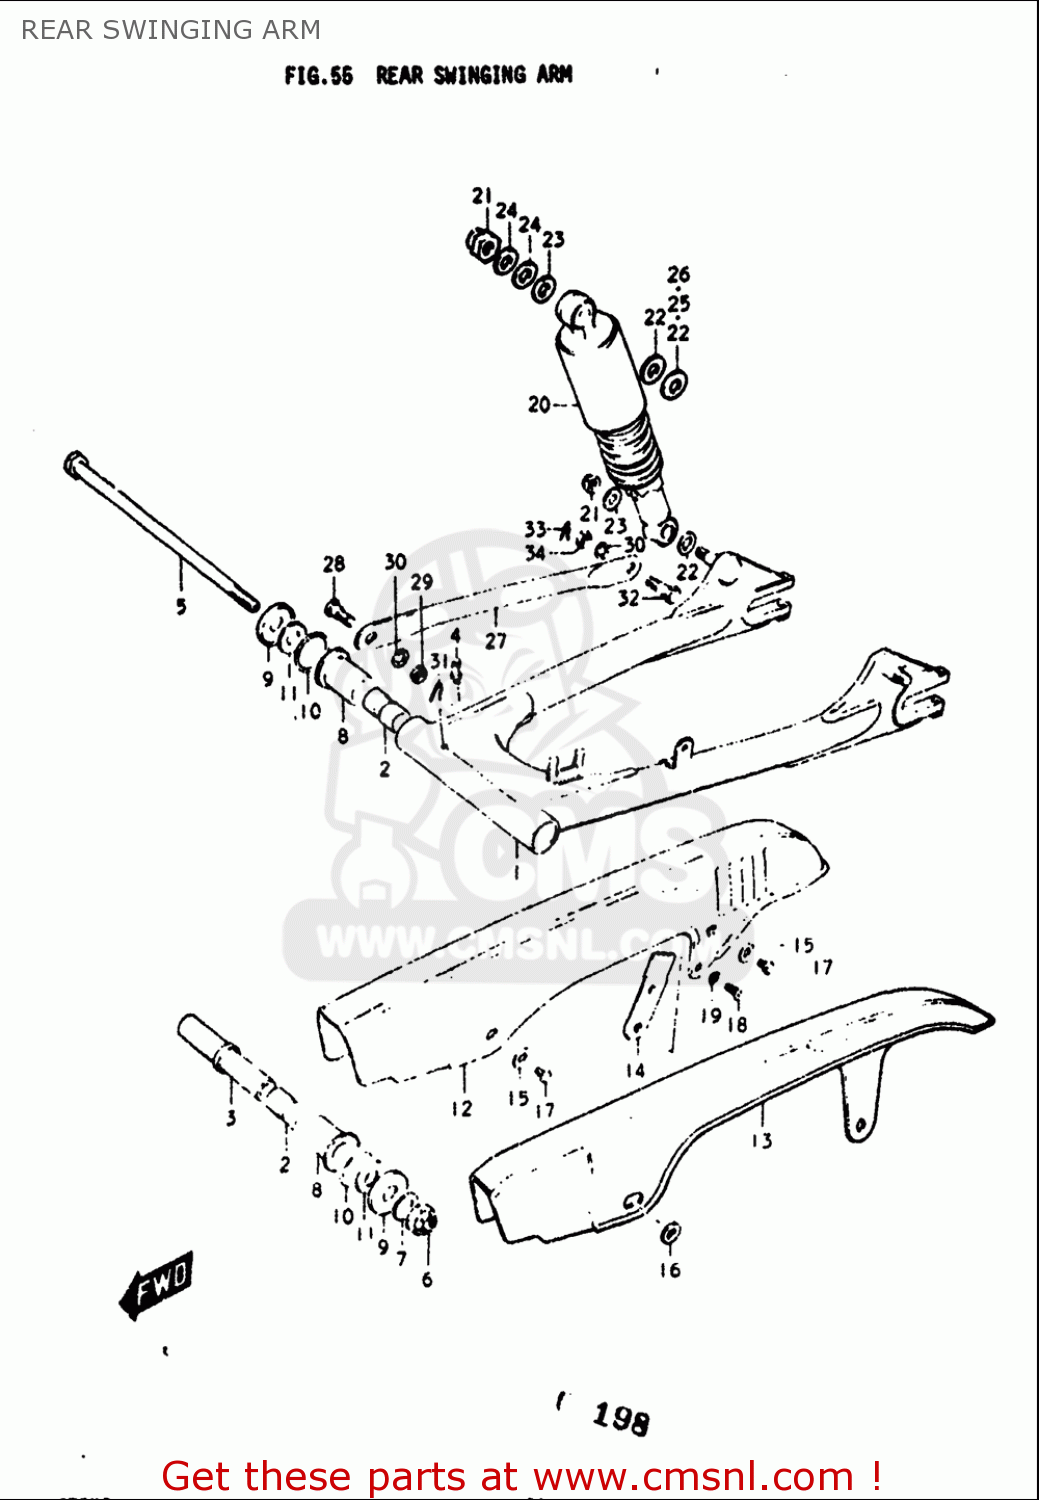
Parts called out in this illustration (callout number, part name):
2	BUSH
4	NIPPLE,GREASE
5	SHAFT,REAR SWING ARM
6	NUT 14MM
7	WASHER
8	SPACER
9	COVER
10	O RING(D:3,ID:29.5)
11	WASHER(14.5X29X2.3)
13	CASE,CHAIN
15	WASHER
16	WASHER(6.5X18X1.6)
17	BOLT(6X8)
18	SCREW
19	LOCK WASHER
21	NUT
22	WASHER
23	WASHER (10.5X24X2.3)
24	WASHER (10.5X25X3.2)
25	WASHER(12.5X24X3.2)
26	WASHER(12.5X24X1.6)
28	BOLT(10X24.5)
29	NUT
30	WASHER,LOCK
31	CLIP
32	BOLT(10X31)
33	NUT
34	CLIP
